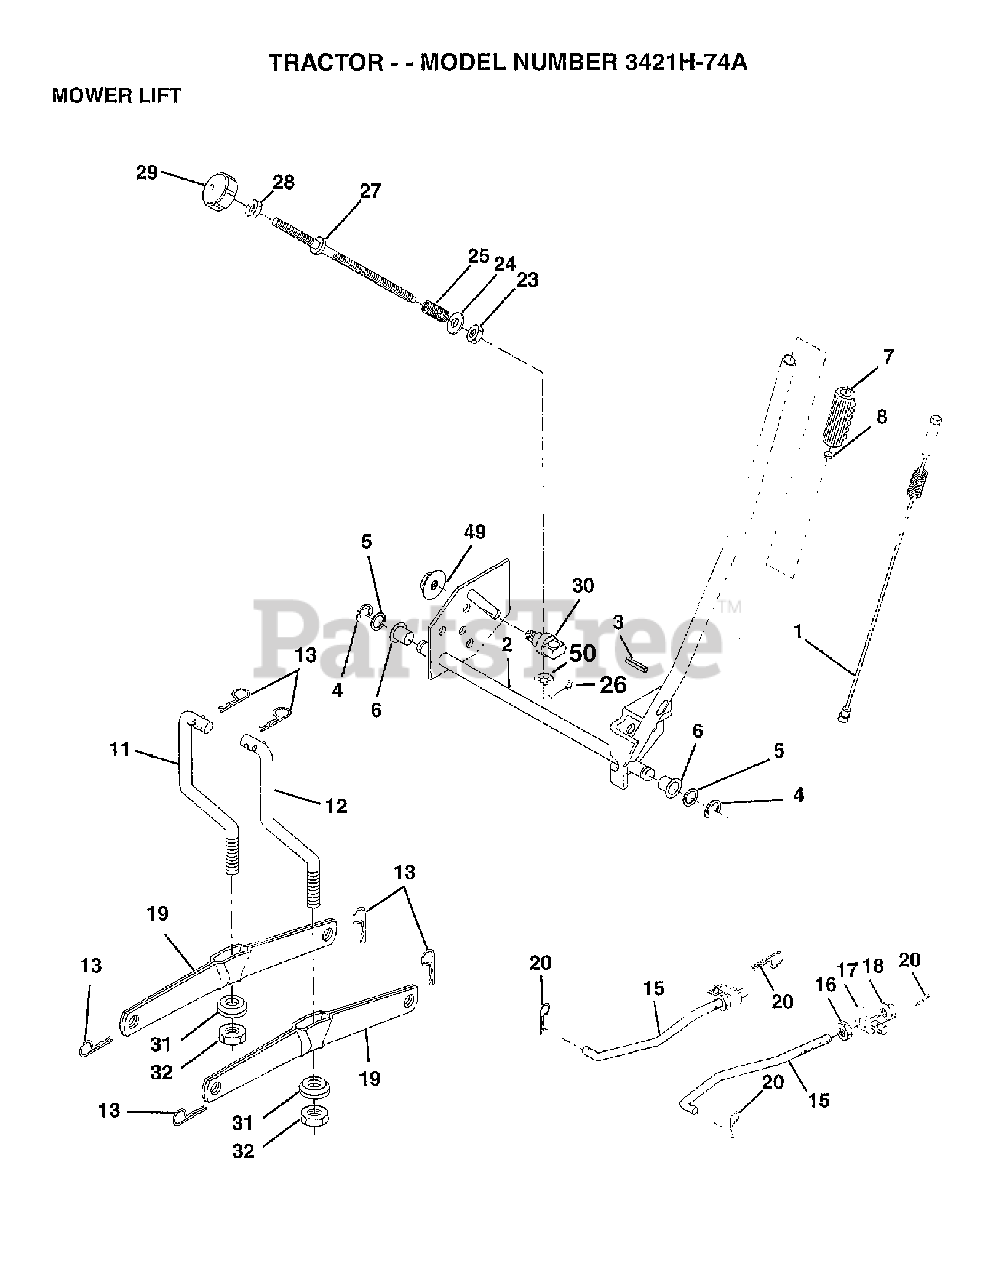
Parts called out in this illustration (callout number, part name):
1	WIRE.ASM.INNER.SP
2	SHAFT.ASM.LIFT.RH.INF
3	PIN GROOVE
4	RETAINING RING LT
6	BEARING.NYLON
7	GRIP
8	PLUNGER BUT KIT
11	LINK LIFT LH
12	Lift Link Assembly, RH
13	RETAINER SPRING
15	FRONT LINK
16	NUT.HEX.JAM.1/2-13
18	NUT.LK.W/WSH.1/2.
19	ARM.REAR.SUSPENSION
20	SPRING RETAINER
24	WASHER
25	SPRING.COMP.INF.H
27	ROD.LIFT.ADJUSTABLE
28	NUT
29	KNOB INF 3/8-16
30	TRUNNION
32	NUT CROWNLOCK 3/8-24
49	Flange Hex Lock Nut, 3/8-16
50	NUT PUSH M
